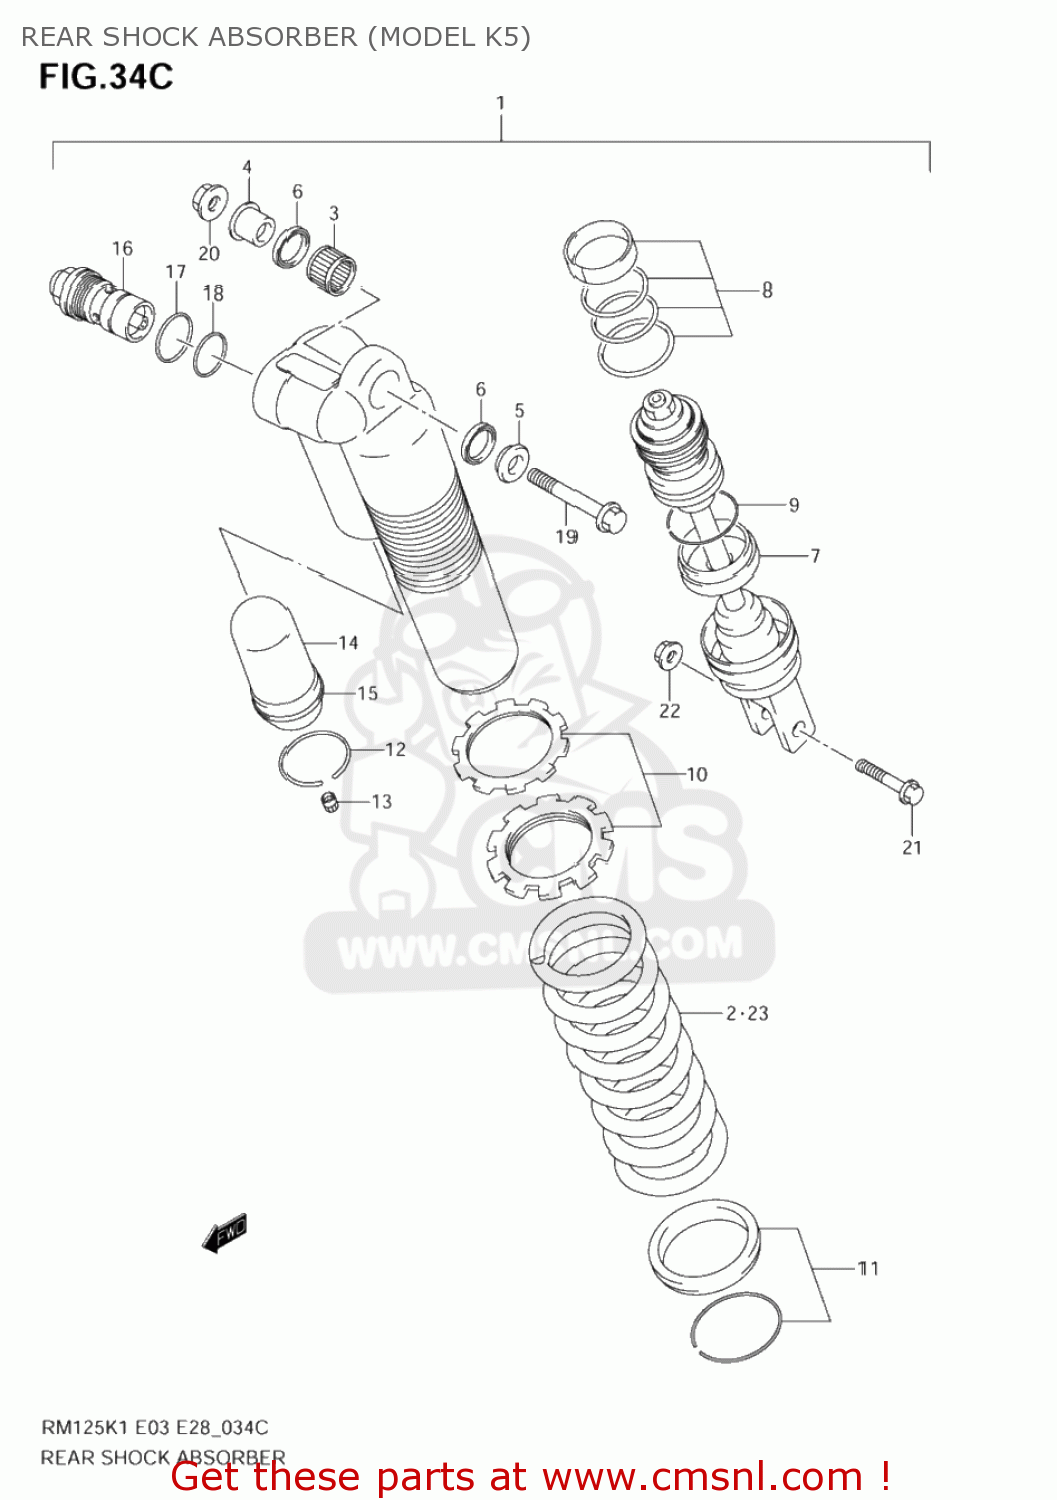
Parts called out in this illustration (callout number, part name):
1	ABSORBER ASSY,RR SHOCK(YELLOW)
2	SPRING,RR(K=5.1)
3	BEARING(16X22X12)
4	SPACER,UPPER BRG,R
5	SPACER,UPPER BRG,L
6	SEAL,OIL(16X22X2.5)
7	ROD,PISTON
8	O RING SET
9	RING,STOPPER
10	ADJUSTER SET
11	SPRING SEAT SET
12	RING,STOPPER
13	CAP
14	BLADDER
15	CAP,CHAMBER
16	BOLT,PLUG
17	O RING
18	O RING,CTR BOLT UPR
19	BOLT(10X65)
20	NUT
21	BOLT,RR SHOCK ABSORBER LWR
22	NUT
23	SPRING,RR(K=4.6)
